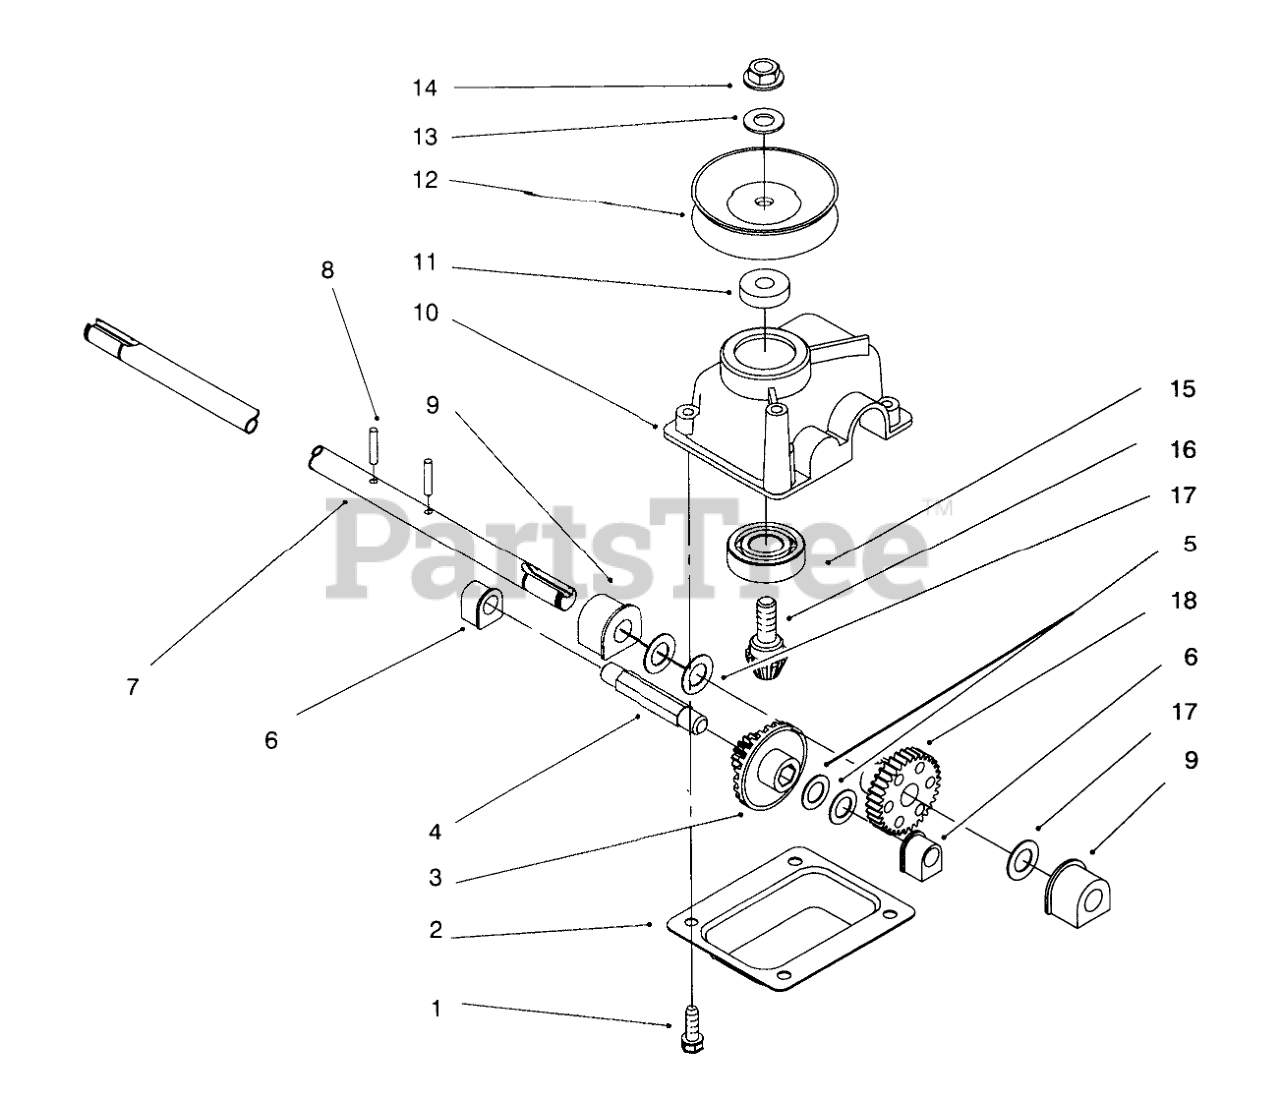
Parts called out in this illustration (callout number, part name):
1	SCREW-HWHTF
2	Cover-Gear Case
3	Gear-Bevel
4	SHAFT-INTERMEDIATE
5	WASHER-THRUST
6	BUSHING
7	OUTPUT SHAFT
8	SPIROL PIN H D
9	BUSHING
10	GEARCASE
11	SPACER
12	PULLEY-DRIVEN HALF
13	WASHER-FLAT
14	NUT-HEX
15	BEARING-BALL
16	Gear-Pinion
17	WASHER-PLAIN
18	GEAR
